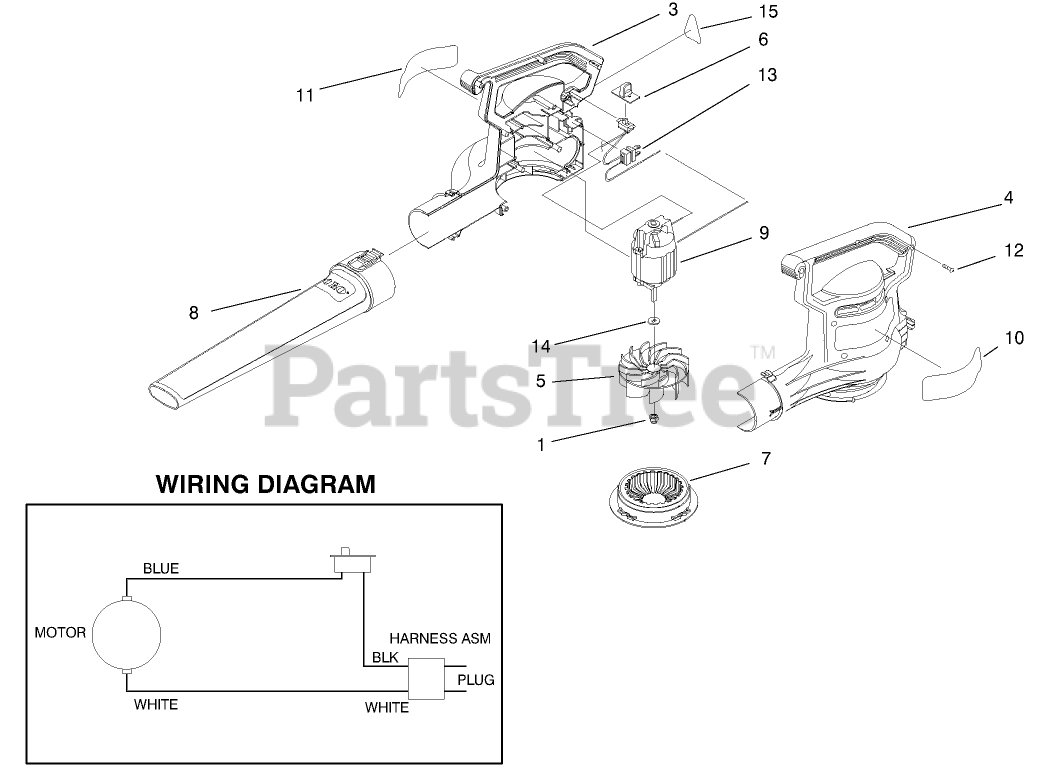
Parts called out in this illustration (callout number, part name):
1	NUT-LOCK, NI
5	IMPELLER, BLOWER
7	COVER - INLET
10	DECAL - POWER SWEEP
11	DECAL - WARNING
12	SCREW-PPH
14	WASHER-FLAT
15	DECAL - INFORMATION
